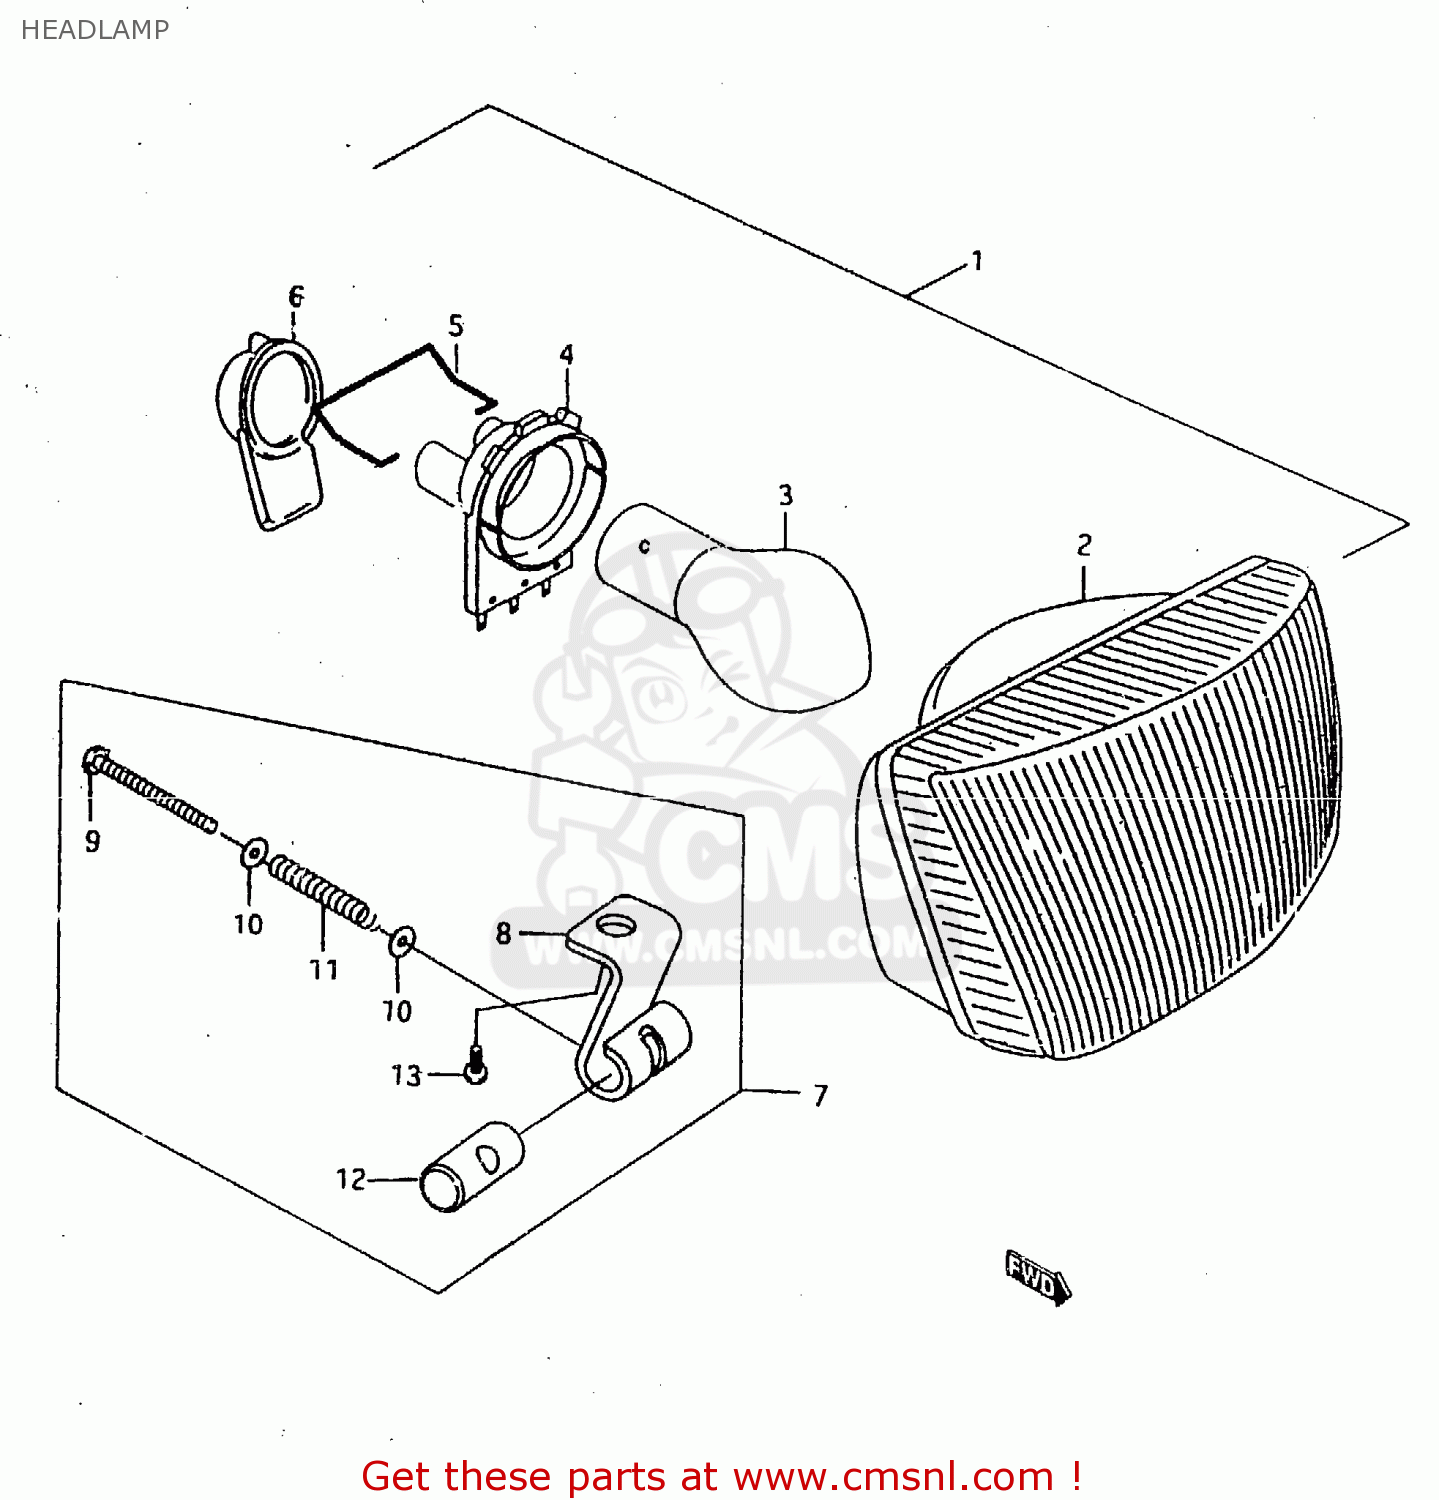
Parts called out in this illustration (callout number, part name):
1	HEADLAMP
2	UNIT
3	BULB (12V, 15W)
4	SOCKET
5	SOCKET SPRING
6	COVER, SOCKET
7	BRACKET SET
8	BRACKET
9	BOLT
10	WASHER
11	SPRING
12	NUT
13	SCREW
